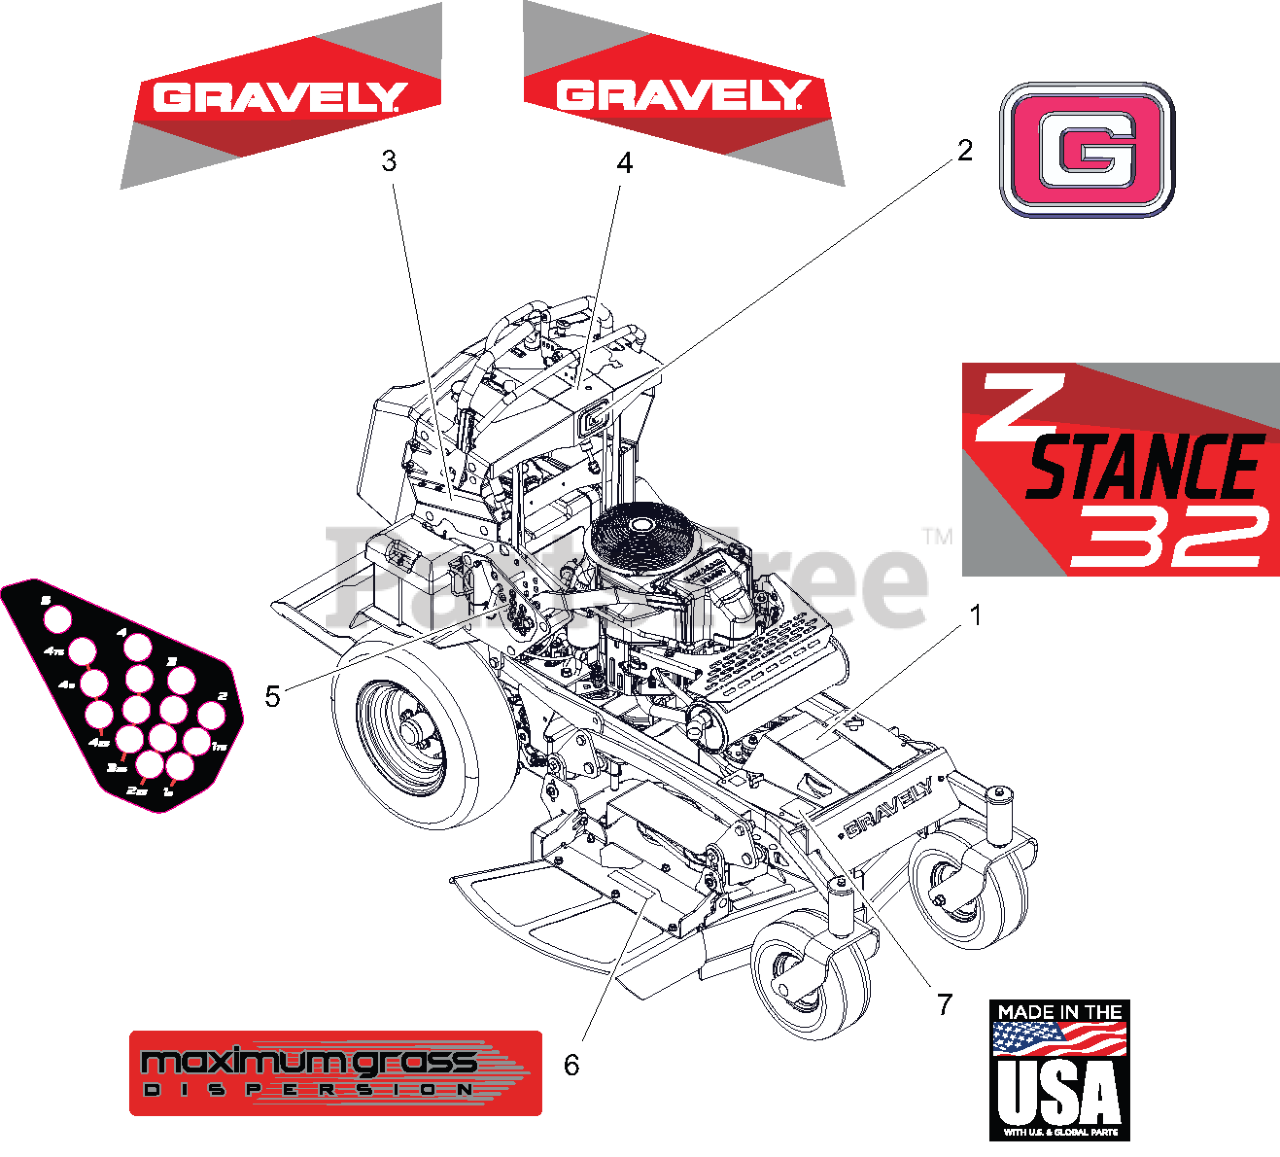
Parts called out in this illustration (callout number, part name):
1	DECAL- Z-STANCE 32"
2	DECAL, GRAVELY BRAND
3	DECAL,RH GRAVELY LOGO
4	DECAL- LH GRAVLEY LOGO
5	DECAL- DECK - HEIGHT ADJUST
6	DECAL, DECK - MAX GRASS
7	DECAL, MADE IN USA
